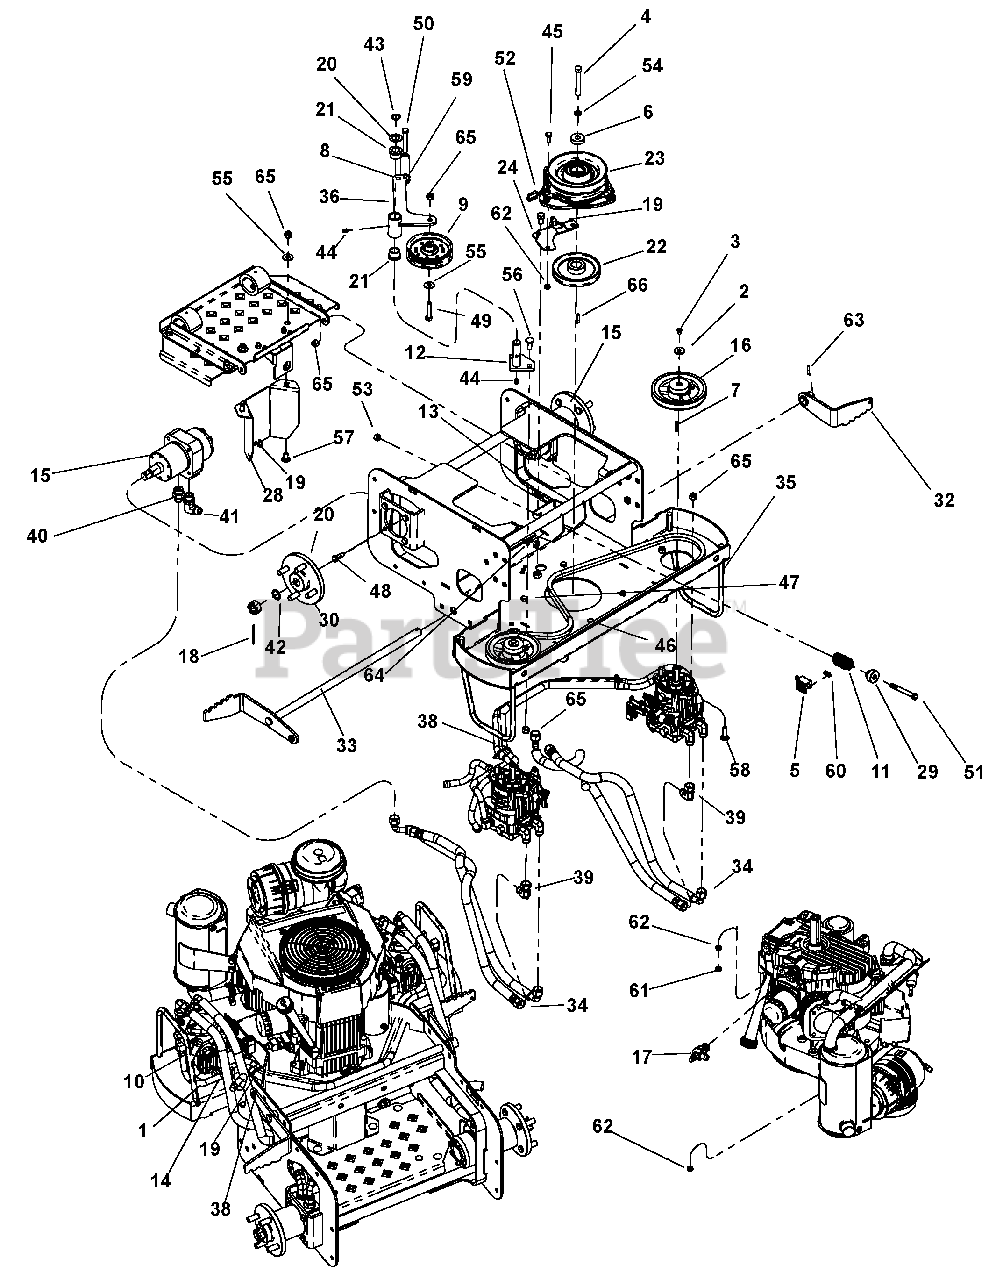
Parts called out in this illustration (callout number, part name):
1	Hose, 3/8 SAE30r7 Fuel & Oil
2	Washer, .250 Wide Heavy Flat Y
3	Bolt, M6 x 1.00 x 10 Hex 8.8 Y
4	Bolt, 7/16-20 x 3.00 Hex 5 Y
5	Switch (N.0.)
6	Spacer, .468 x 1.38 x .375 Y
7	Key, M5 x M5 x M30 RD
8	Spring, Ext .900 x .135x4.50 Y
9	Pulley, V-belt 4.00x.379 w/Bearing
10	Clamp, Hose - 1/2" Pinch
11	Spring, Com 1.22x.162x2.50 Y
12	Idler Post
13	Decal, Warning - Hot Surfaces
14	Fitting, Tun 3/8 Hose
15	Motor, Wheel Hgm-12p-7172
16	Assy, Pump Pulley w/Set Screw
17	Fitting, Oil Drain
18	Pin, Cot .125 x 2.00 EXTP Y
19	Tie Wrap, Black
20	Bushing, Machine .750 x 1.25 x .048
21	Bushing, Flange .750 x 1.000 x .750 x 1.250 Bracket
22	Pulley, V-belt 4.78pd x 1.000
23	Clutch Assembly, Ogura
24	Plate, Clutch Dog
25	Engine, Kawasaki 19hp FH580V
26	Assembly, Hyd Pump
27	Assembly, Hyd Pump
28	Cover, Operator Presence Control
29	Washer, Spring Y
30	Assy, Rear Wheel Hub
31	Belt, HA 68.2 EL AMD OHR
32	Weldment, RH Brake Arm
33	Weldment, LH Brake Shaft
34	Hose, Hyd 1/2 x 26 1/2 Ezflex
35	Weldment, Frame 34
36	Weldment, Idler Pivot
37	Assy, Foot Plate
38	Abrasion Sleeve
39	Adapter, .75 FESW x 3/4MJICX90
40	Adapter, Hydraulic Steel 7/8 "O" To .75
41	Adapter, 8MJ-10MB90
42	Shim, .020 x .787 x 1.102
43	Ring, Retaining-External .750 x .042
44	Grease Zerk, 1/4-28 Straight .69 LG
45	Bolt, Hex .31-18 x .75 Grade 5
46	Bolt, Hex .31-18 x 1.50 Grade 5
47	Bolt, Hex .31-18 x 1.75 Grade 5
48	Bolt, 3/8-16 x 1.00 Hex 5
49	Bolt, 3/8-16 x 1.75 Hex 5
50	Bolt, 3/8-16 x 2.50 Hex 5
51	Bolt, 3/8-16 x 3.25 Hex 5
52	Bolt, 7/16-14 x .750 Hex 5
53	Nut-Hex .31-18
54	Washer-Locking .38 x .094 Regular
55	Washer-Flat-Steel .438 x 1.00 x .083
56	Bolt-Round Head Square Neck .38-16 x 1.00 Grade 5
57	Bolt-Round Head Square Neck .38-16 x 1.00 Grade 5
58	Bolt-Round Head Square Neck .38-16 x 1.25 Grade 5
59	Nut, .38-16 Jam Grade 5
60	Nut-Locking-Nylon 10-24 with Insert
61	Nut-Jam .312-18
62	Nut-Locking-Nylon .312-18
63	Pin-Roll .156 x 1.00
64	Screw, Machine 10-24 x .625 Panhead
65	Nut-Locking-Nylon .38-16
66	Key, .250 x .250 x .995 TPR
